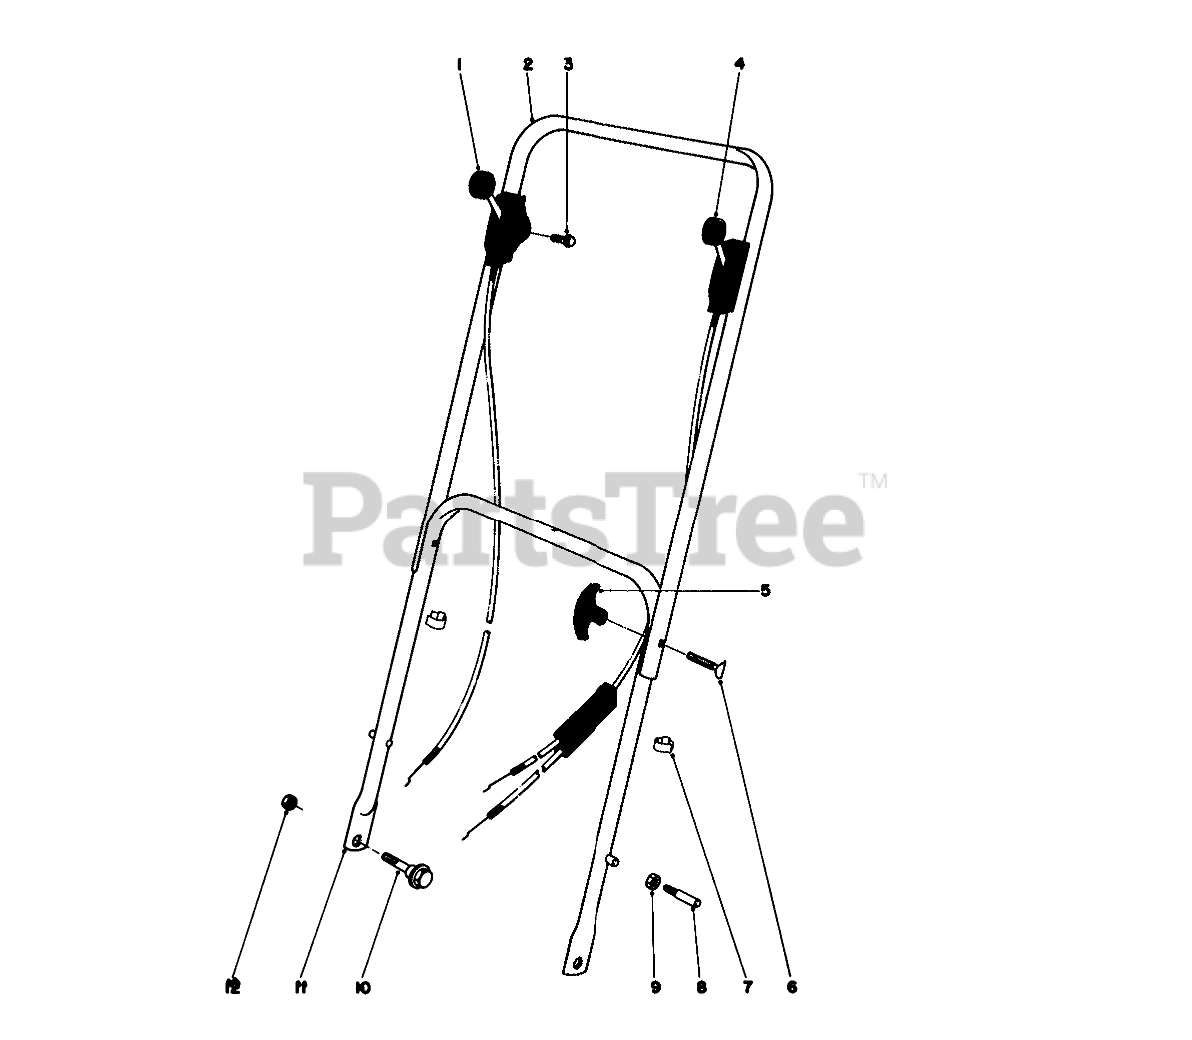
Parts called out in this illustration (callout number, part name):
1	Throttle Control
2	UPPER HANDLE
4	Traction Control
5	Handle Knob
6	HANDLE SCREW
7	BOWDEN CLIP
8	HANDLE PIN
9	Nut
10	SCREW-SHOULDER
11	Lower Handle
12	Nut
